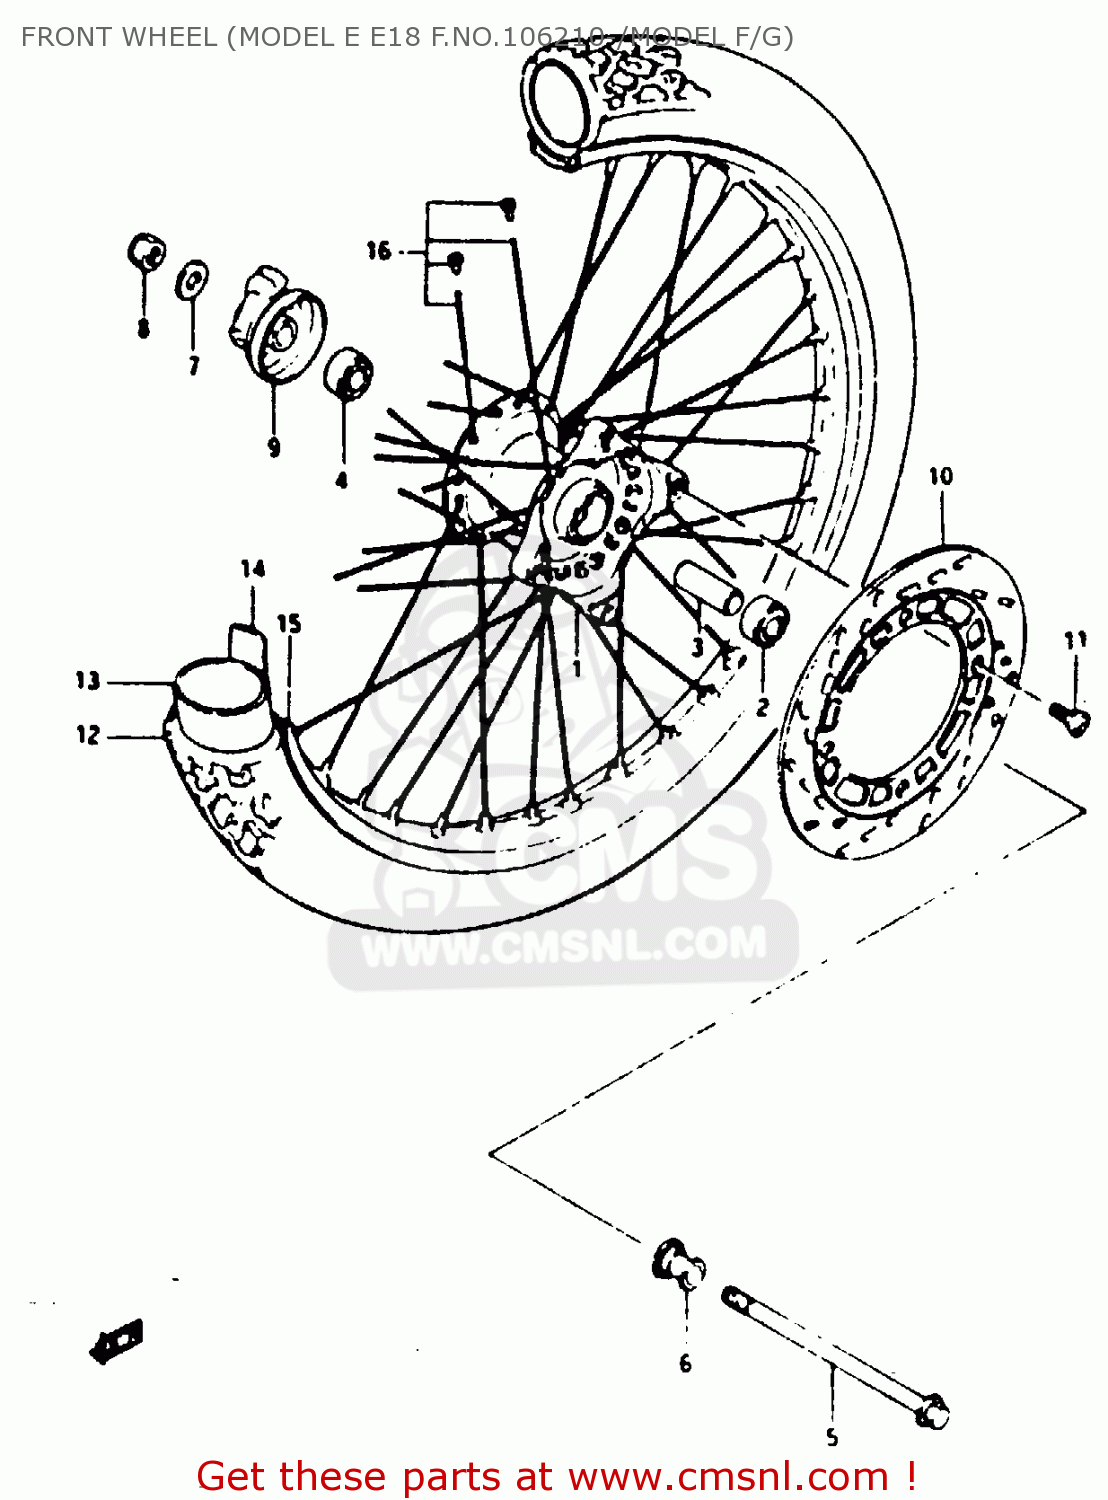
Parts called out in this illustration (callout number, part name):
1	HUB,FRONT
2	BEARING, RH
3	SPACER (12.6X19X60.5)
4	BEARING
5	AXLE,FRONT
6	SPACER,FRONT AXLE,RIGHT
7	WASHER
8	NUT (12MM)
9	BOX ASSY,SPEEDOMETER GEAR
10	DISC,BRAKE
11	BOLT,BRAKE DISC
12	TIRE, FRONT (80/80-21) BS
13	TUBE
14	PROTECTOR,WHEEL,INNER
15	RIM,FRONT WHEEL
16	SPOKE SET, FRONT WHEEL
